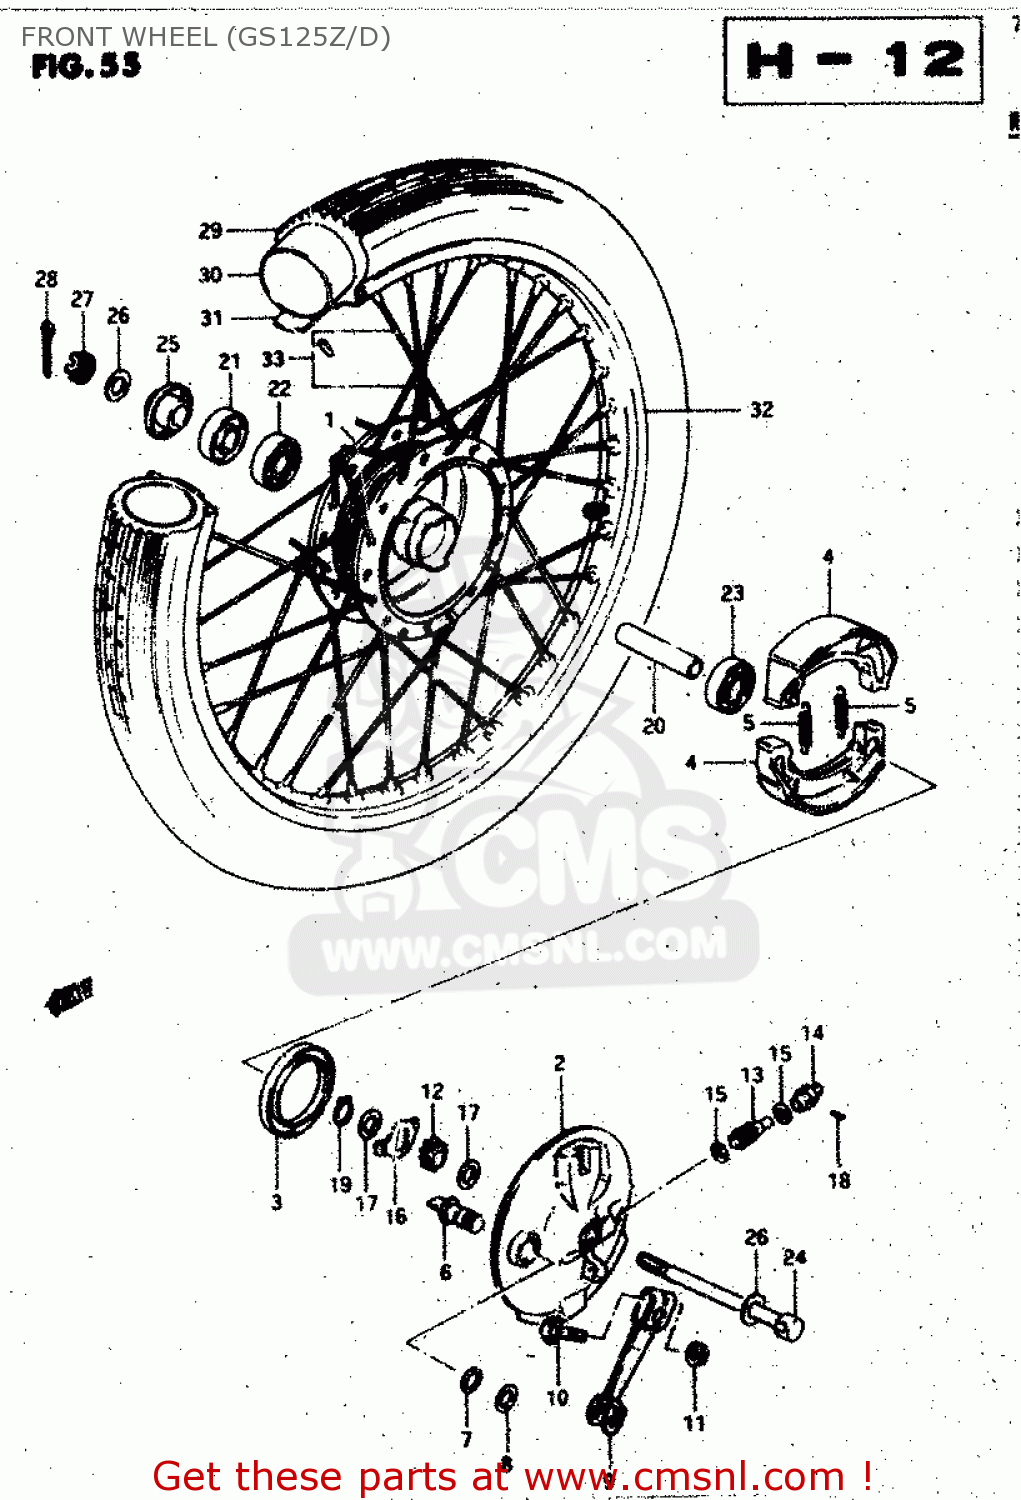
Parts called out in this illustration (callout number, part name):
1	HUB,FRONT
2	PANEL,FRONT BRAKE ANCHOR
3	SEAL,OIL(48X62X7)
4	SHOE,BRAKE
5	SPRING(L:34)
6	CAM,FRONT BRAKE
7	O-RING (D:2.4 ID:13.8)
8	WASHER (14.5X22X1.6)
9	LEVER,FR BRAKE CAM
10	BOLT 6X35
11	NUT
12	GEAR,SPEEDOMETER(NT:24)
13	PINION,SPEEDOMETER(NT:9)
14	BUSH,METER GEAR OUTER
15	WASHER (5.1X9X0.4)
16	DRIVER,SPEEDOMETER GEAR
17	WASHER(18.5X24X1)
18	SCREW
19	CLIP
20	SPACER(12.6X19X47)
21	OIL SEAL(17X38X5)
22	BEARING
23	BEARING
24	AXLE,FRONT
25	SPACER,FR AXLE,R
26	WASHER
27	NUT 12MM
28	COTTER PIN
29	TIRE,FRONT
30	TUBE,INNER
31	PROTECTOR,INNER TUBE
32	RIM,FR WHEEL 1.60X18
33	SPOKE SET,FRONT
